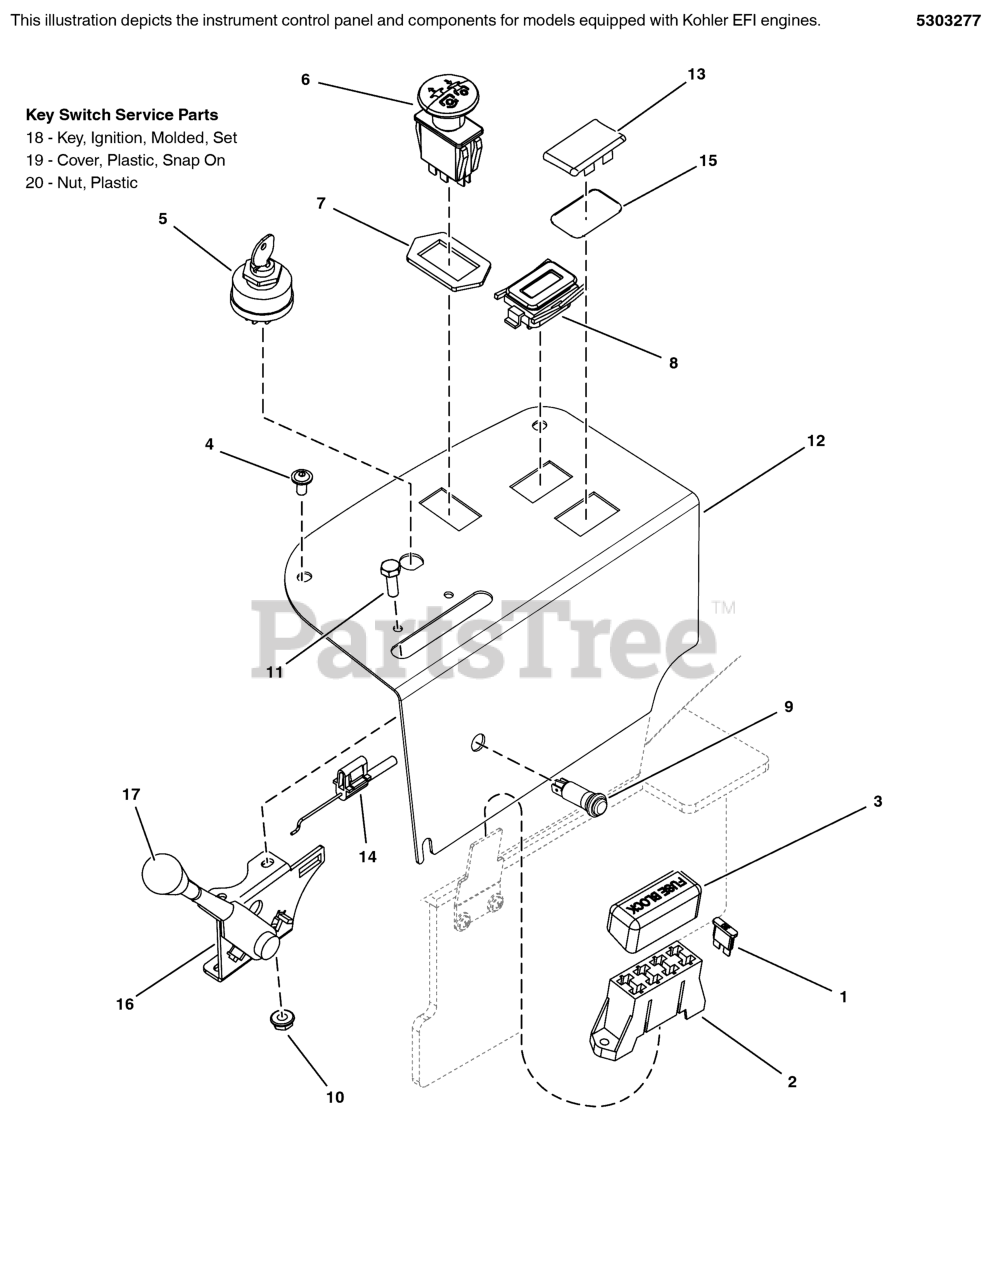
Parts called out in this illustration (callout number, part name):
1	FUSE, ATO 20 AMP
2	FUSE, BLOCK
3	COVER, VINYL FUSEBLOCK
4	SCREW, 1/4-20 X 1/2" ALLEN BH
5	SWITCH, IGNITION, 6 POST
6	SWITCH, BLADE ENGAGEMENT
7	RING, SWITCH RETAINER
8	HOUR METER, ASSEMBLE
9	LIGHT, INDICATOR, PANEL, LED, RED
10	NUT, #10-24 HEN NYLON LOCK
11	SCREW, #10-24 X 3/4"
12	PLATE, CONTROL, KOHLER, IS2000Z - BLK
13	PLUG, .820X1.44 HOLE, BLACK PLASTIC
14	CABLE, THROTTLE 47"
15	O-RING, 7/8" ID X 1/16"
16	LEVER, THROTTLE CONTROL, HEAVY-DUTY
17	THROTTLE CONTROL HANDLE/KNOB
18	KEY, IGNITION MOLDED SET
19	COVER, PLASTIC, SNAP ON
20	PLASTIC NUT
